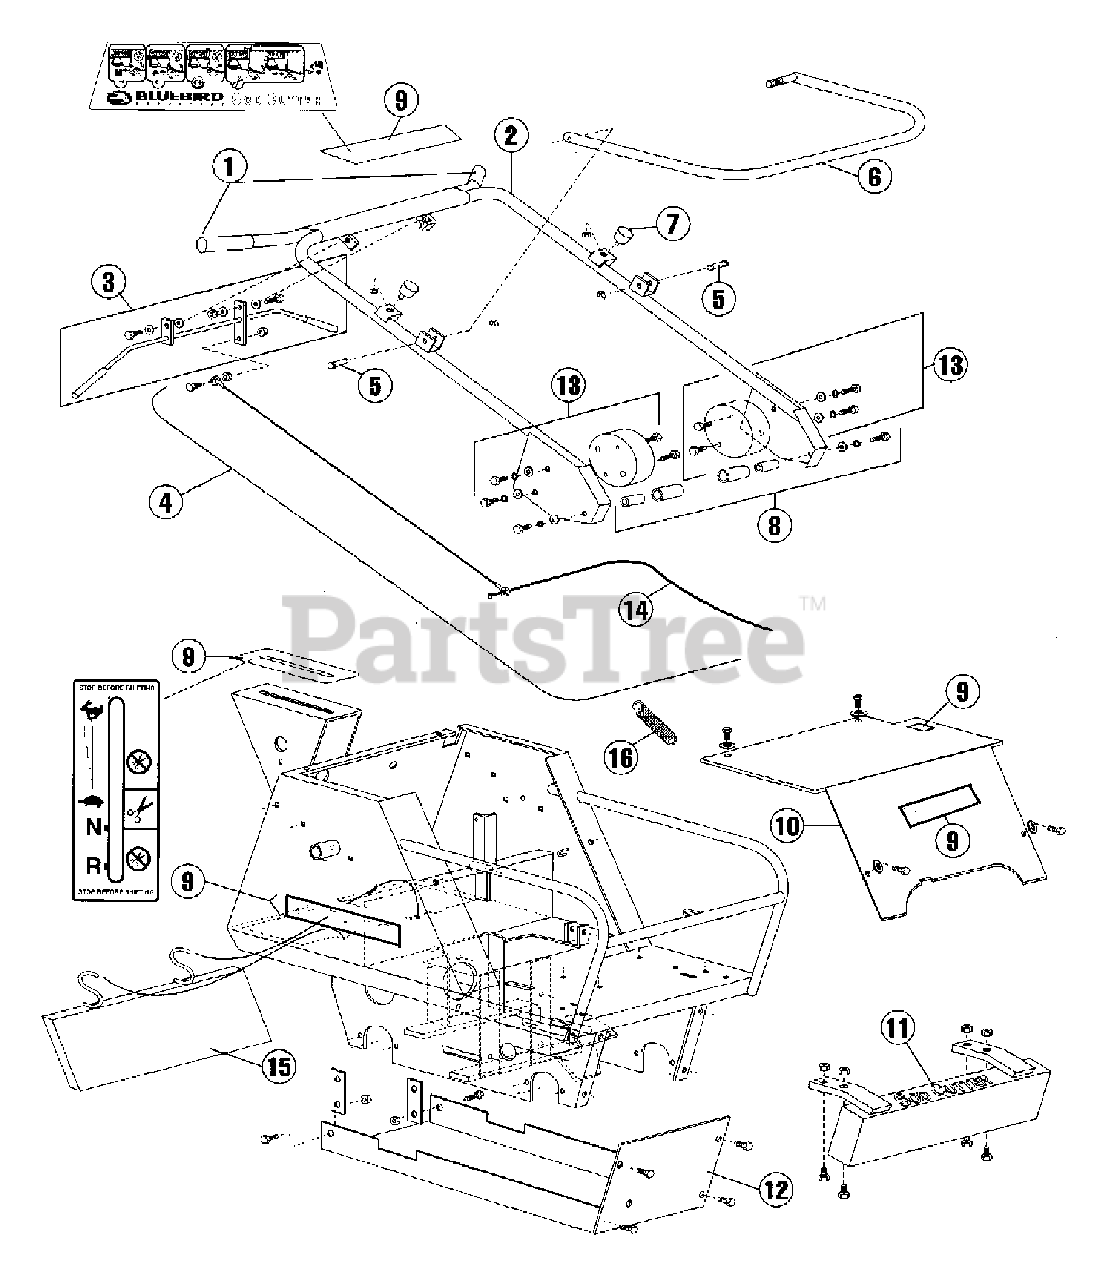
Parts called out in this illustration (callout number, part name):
1	Grips pair
2	Handle kit
3	Clutch/throttle control kit, with grips and hardware
4	Cable, throttle cable kit
5	Pins, depth handle with clip
6	Blade engagement lever
7	Bumpers, handle
8	Decal kit,SC18
9	Stand off kit
10	Shield cover kit, upper housing with hardware
11	Weight weldment with hardware
12	Skid pan
13	Handle attachment hardware kit
14	Throttle cable, carb
15	Deflector with "S" links
16	Spring
